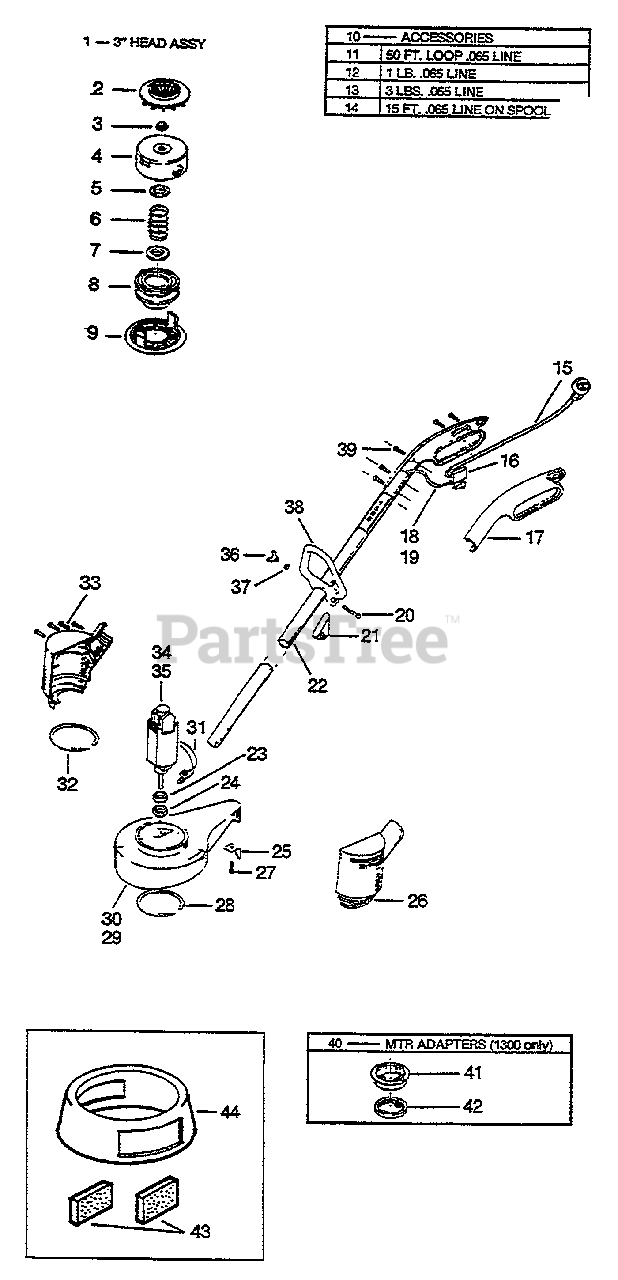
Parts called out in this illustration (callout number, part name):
1	HEAD ASSY
3	ARBOR NUT
4	3" TWIN LINE HEAD
5	SPRING PLATE
6	SPRING
7	SPRING PLATE
8	SPOOL
9	CAP
10	ACCESSORIES
11	50 FT.LOOP .065 LINE
12	1 LB. .065 LINE
13	3 LB. .065 LINE
14	15 FT. .065 LINE ON SPOOL
17	TRIGGER HSG. SET
18	HARNESS (1500)
19	HARNESS (1300)
20	HANDLE BOLT
21	ASSIST HANDLE SUPPORT
23	NUT (1300)
24	NUTS (1500)
25	CUT OFF BLADE
26	MOTOR HSG. SET
27	BLADE SCREW
28	SKIRT SNAP RING
29	SKIRT MODEL 1500
30	SKIRT MODEL 1300
31	WIRE CONNECTOR
32	SNAP RING MOTOR HSG.
33	HOUSING SCREW
34	MOTOR (1300)
35	MOTOR (1500)
38	ASSIST HNDL
39	HANDLE SCREW
40	MOTOR ADAPTERS
41	UPPER MTR ADAPTER
42	LOWER MOTOR ADAPTOR
43	AIR FILTER
44	AIR FILTER CAP
